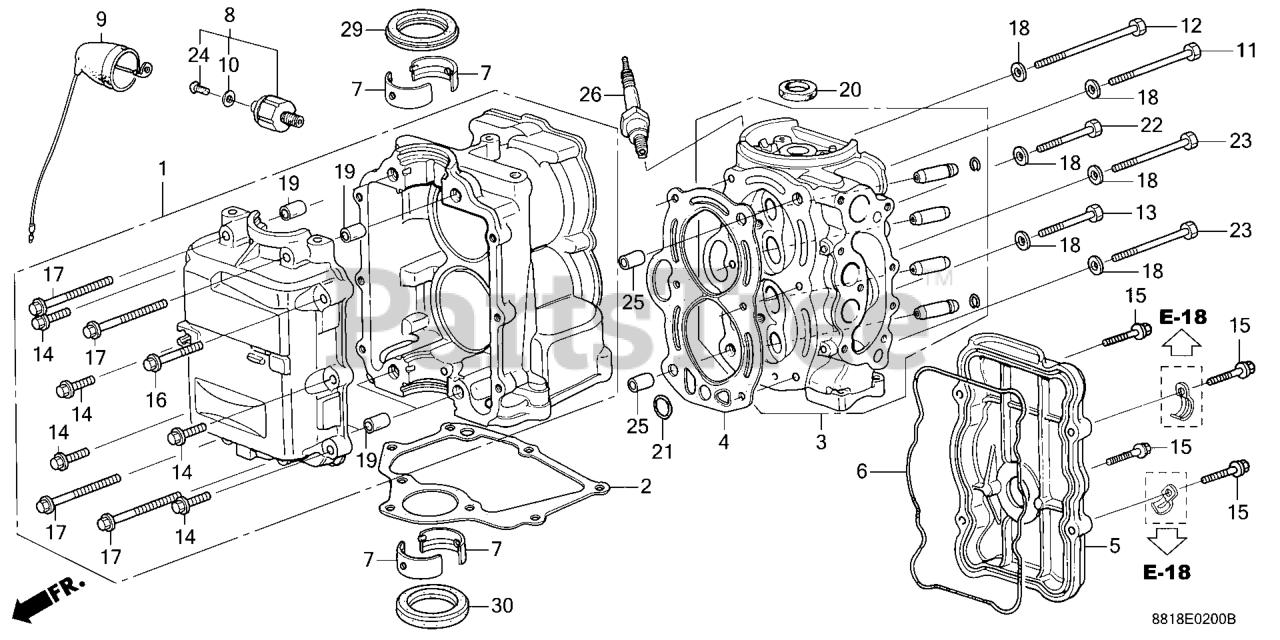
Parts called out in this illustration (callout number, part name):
1	CYLINDER ASSY. *NH8* (DARK GRAY)
2	GASKET, OIL PAN
3	CYLINDER HEAD *NH8* (DARK GRAY)
4	GASKET, CYLINDER HEAD
5	COVER, CYLINDER HEAD *NH8* (DARK GRAY)
6	GASKET, CYLINDER COVER
7	BEARING, CRANKSHAFT
8	SWITCH, OIL PRESSURE
9	WIRE, OIL PRESSURE SWITCH
10	WASHER (4MM)
11	BOLT, HEAD (8X70)
12	BOLT, HEAD (8X94)
13	BOLT, HEX. (8X55)
14	BOLT, FLANGE (6X25)
15	BOLT, FLANGE (6X28)
16	BOLT, FLANGE (6X35)
17	BOLT, FLANGE (8X45)
18	WASHER, HEAD (8MM)
19	PIN, DOWEL (10X12)
20	OIL SEAL (16X28X6)
21	O-RING (10.8X2.4) (ARAI)
22	BOLT, HEX. (8X50)
23	BOLT, HEX. (8X65)
24	SCREW, PAN (4X6)
25	PIN A, DOWEL (10X16)
26	SPARK PLUG (DR-4HS) (NGK)
26	SPARK PLUG (DR5HS) (NGK)
26	SPARK PLUG (X16FSR-U) (DENSO)
27	GUIDE, VALVE (OVER SIZE)
28	GUIDE, EX. VALVE (OVER SIZE)
29	OIL SEAL A (30X42X7)
30	OIL SEAL B (30X42X7)
